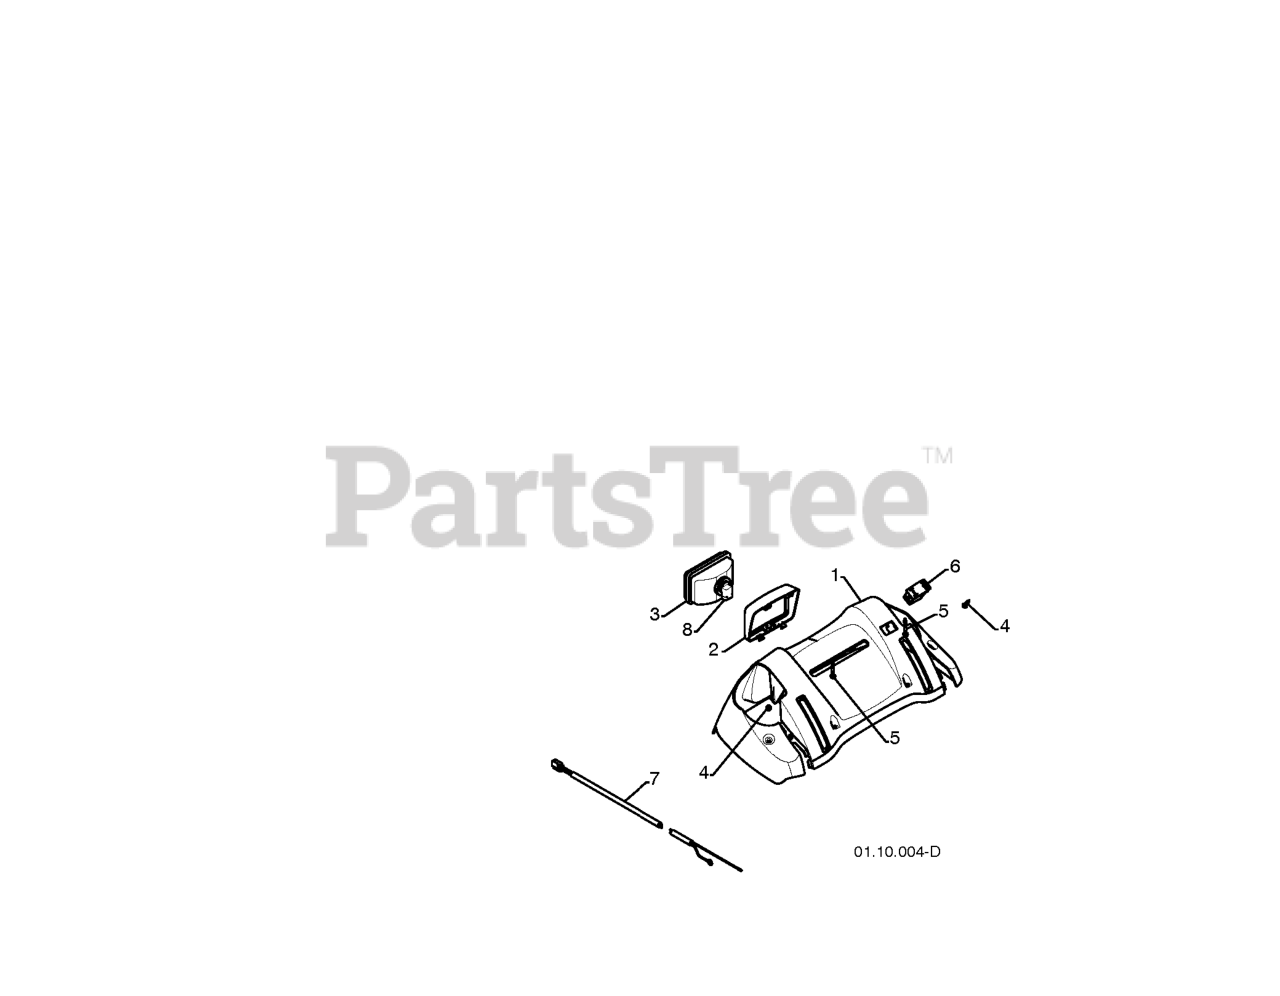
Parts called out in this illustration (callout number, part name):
1	PANEL.CONSOLE.
2	BEZEL.HEADLIGHT
3	HEADLIGHT.HALOGEN.SNOW
4	SCREW, HEX HEAD, TAPPING
5	SCREW, HEX HD TAPPING #10-24 1
6	SWITCH.HEATED.GRIP
7	HARNESS.WIRE.LIGHT/GRIP.SNOW
8	BULB.HEADLIGHT.HALOGEN.
